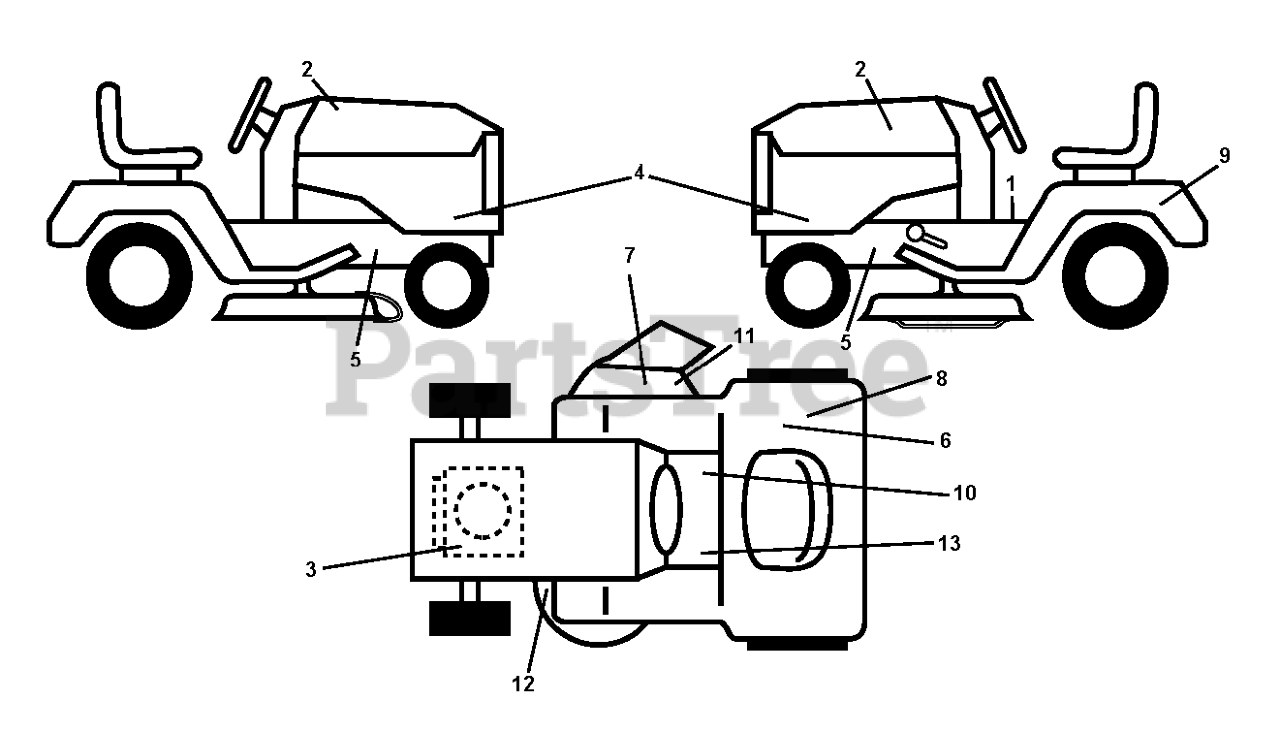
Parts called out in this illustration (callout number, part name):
1	LABEL
2	DECAL.HOOD.LOGO.ORANGE.HUSQVAR
3	DECAL
6	DECAL 80 DBA
7	DECAL.INTERNATIONL.CUTFINGER
8	DECAL
9	DECAL BTRY SYMBOLS
10	DECAL PARK BRAKE
11	DECAL, DEFLECT WARNING
12	DECAL.V-BELT.SCHEMATIC.36/38/9
13	DECAL
